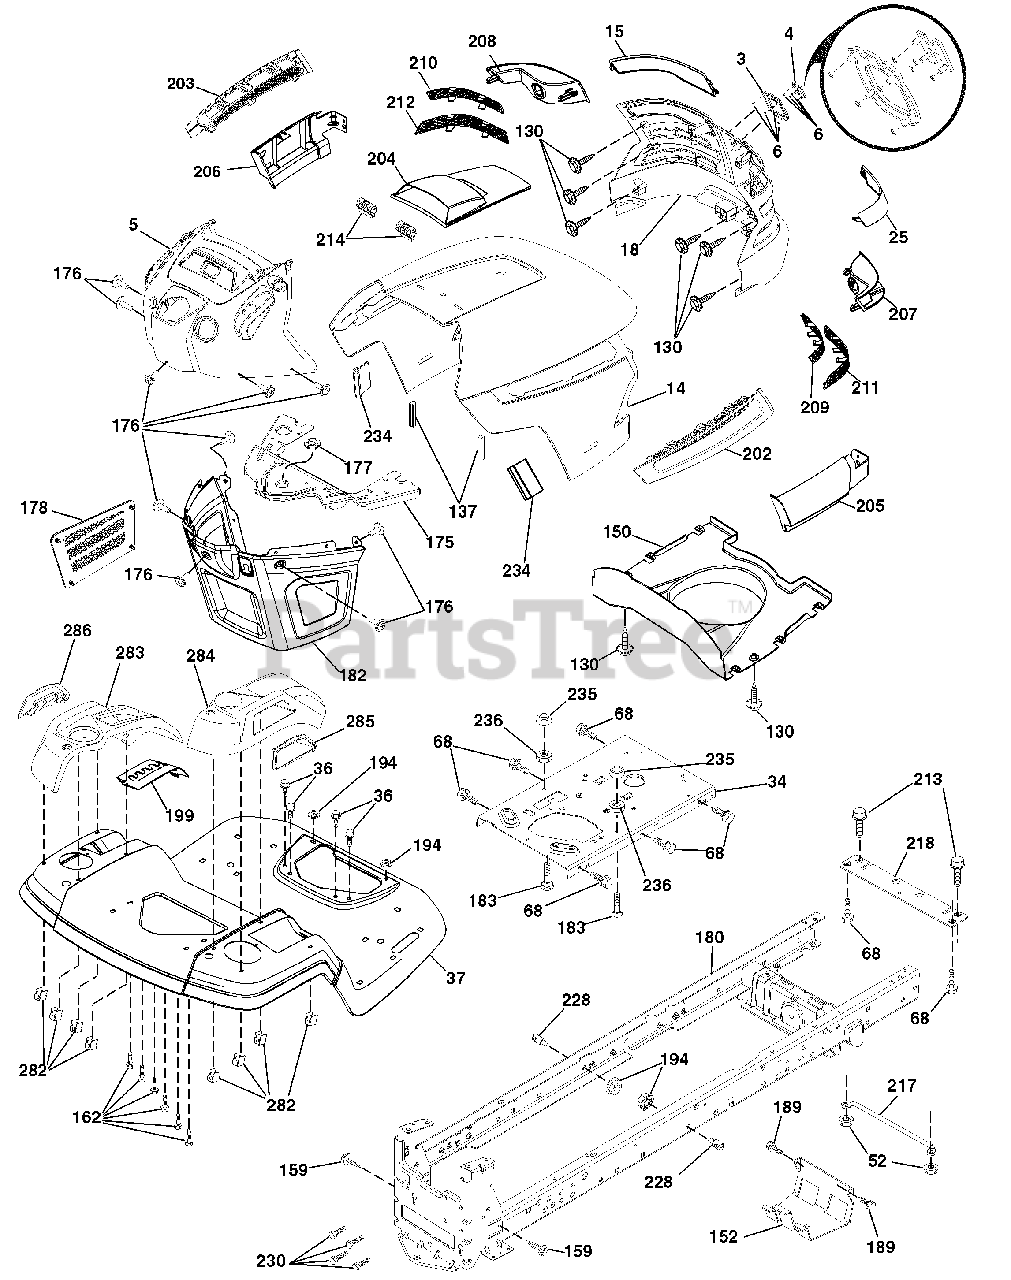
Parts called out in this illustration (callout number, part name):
3	Trim, Husq.
4	Logo
14	Hood
18	Grille/Lens Asm.
34	Plate Engine
36	Screw 5/16-18 x 3/4
37	Fender
52	Nut Lock 5/16-18
68	Screw Thdrol 5/16-18 x 1/2
130	Screw 10 x 0.750 BOS Thread
137	Bumper Dash
152	Shield Browning
159	Screw 3/8-16 x 3/4
175	Crossmember
176	Screw 10-24 x 5/8
177	Bushing Steering
178	Cargo Net Asm.
180	Chassis
181	Bushing Mtg. Fender Crgo
182	Dash Lower
183	Bolt Fin Hex 5/16-18 unc x 1-1/4
189	Screw 5/16-18 x 3/4
194	Nut Lock Hex Flange 5/16-18
199	Plate Deck Lift
202	Vent Side Hood RH
203	Vent Side Hood LH
204	Vent Top Hood
205	Skirt Hood Side RH
206	Skirt Hood Side LH
209	Insert Hex Top RH
210	Insert Hex Top Lh
211	Insert Hex Bottom RH
212	Insert Hex Bottom LH
213	Bolt 5/16-18 x 3/4
214	Clip Retainer Tinner
218	X-Piece Hood Stop
228	Stud Fastner
230	Bolt Shoulder 5/16-18
234	Bumper Hood
235	Spacer Fender
236	Nut Lock 5/16-18 UNC
282	Clip Retainer Console
283	Console Deck Lift
284	Console Shift
285	Console Insert RH
286	Console Insert LH
287	Screw 1/4-20 X 3/8
